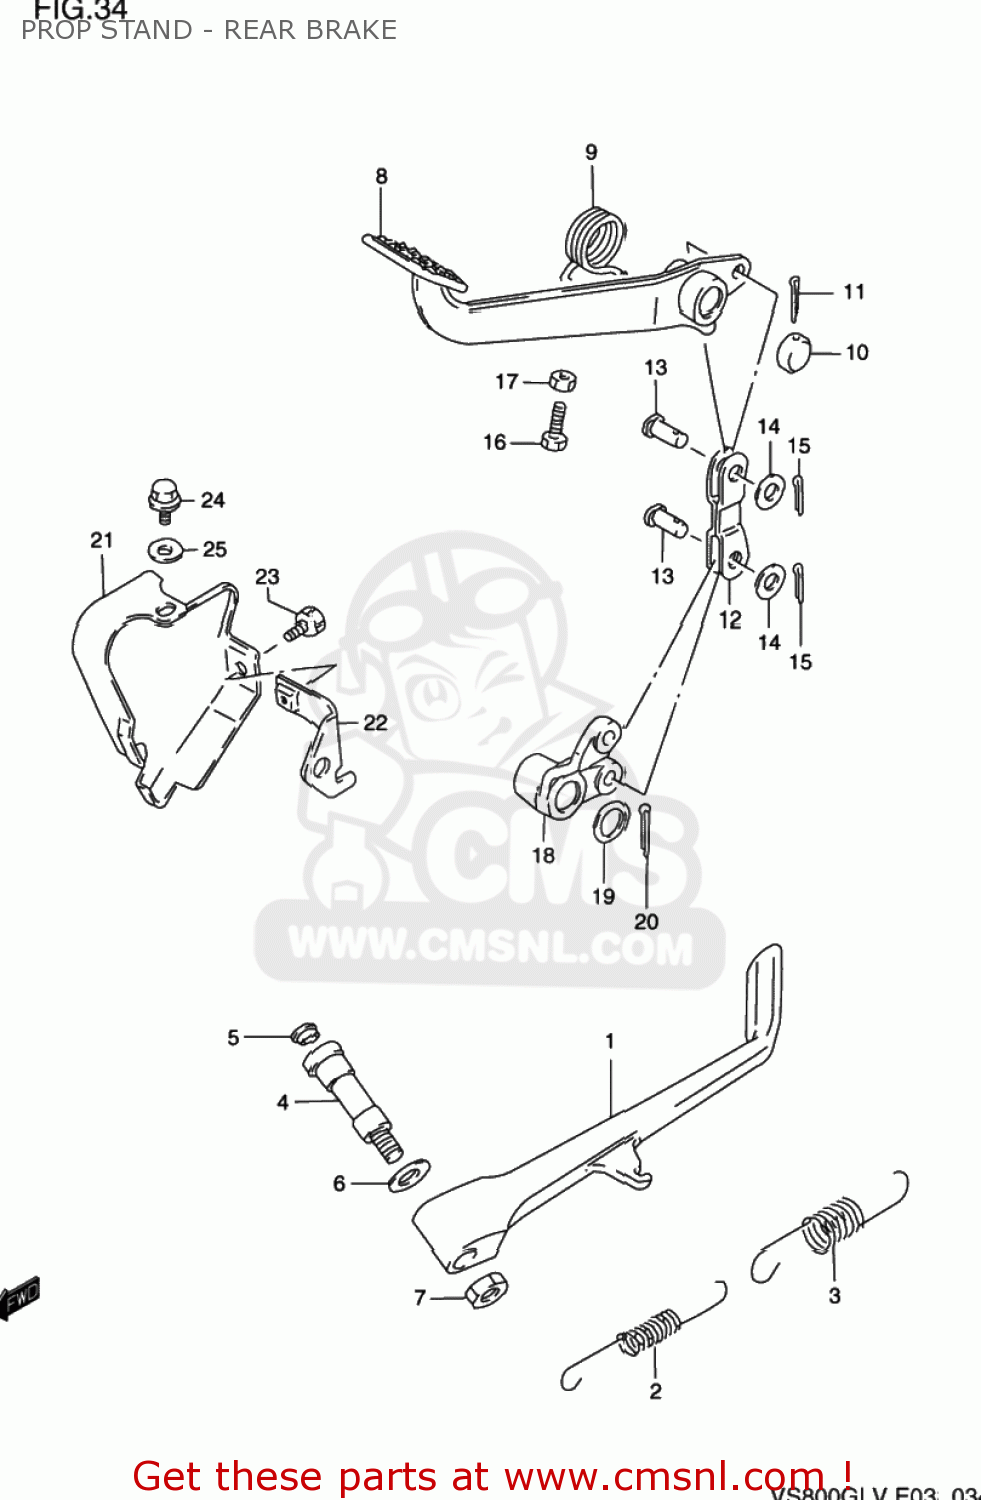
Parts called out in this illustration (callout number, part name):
1	STAND,PROP
2	SPRING
3	SPRING
4	BOLT,PROP STAND
5	CAP
6	THRUST WASHER
7	NUT
8	PEDAL,BRAKE
9	SPRING
10	CAP,BRAKE PEDAL
11	COTTER PIN
12	LINK COMP,BRAKE ROD NO
13	PIN
14	WASHER
15	PIN
16	BOLT
17	NUT
18	ARM,BRAKE PEDAL LINK
19	WASHER (16.2X22X1)
20	COTTER PIN
21	COVER,BRAKE
22	BRACKET COMP,BRAKE COVER
23	SCREW(6X10)
24	BOLT
25	WASHER(6.5X15X1.0)
